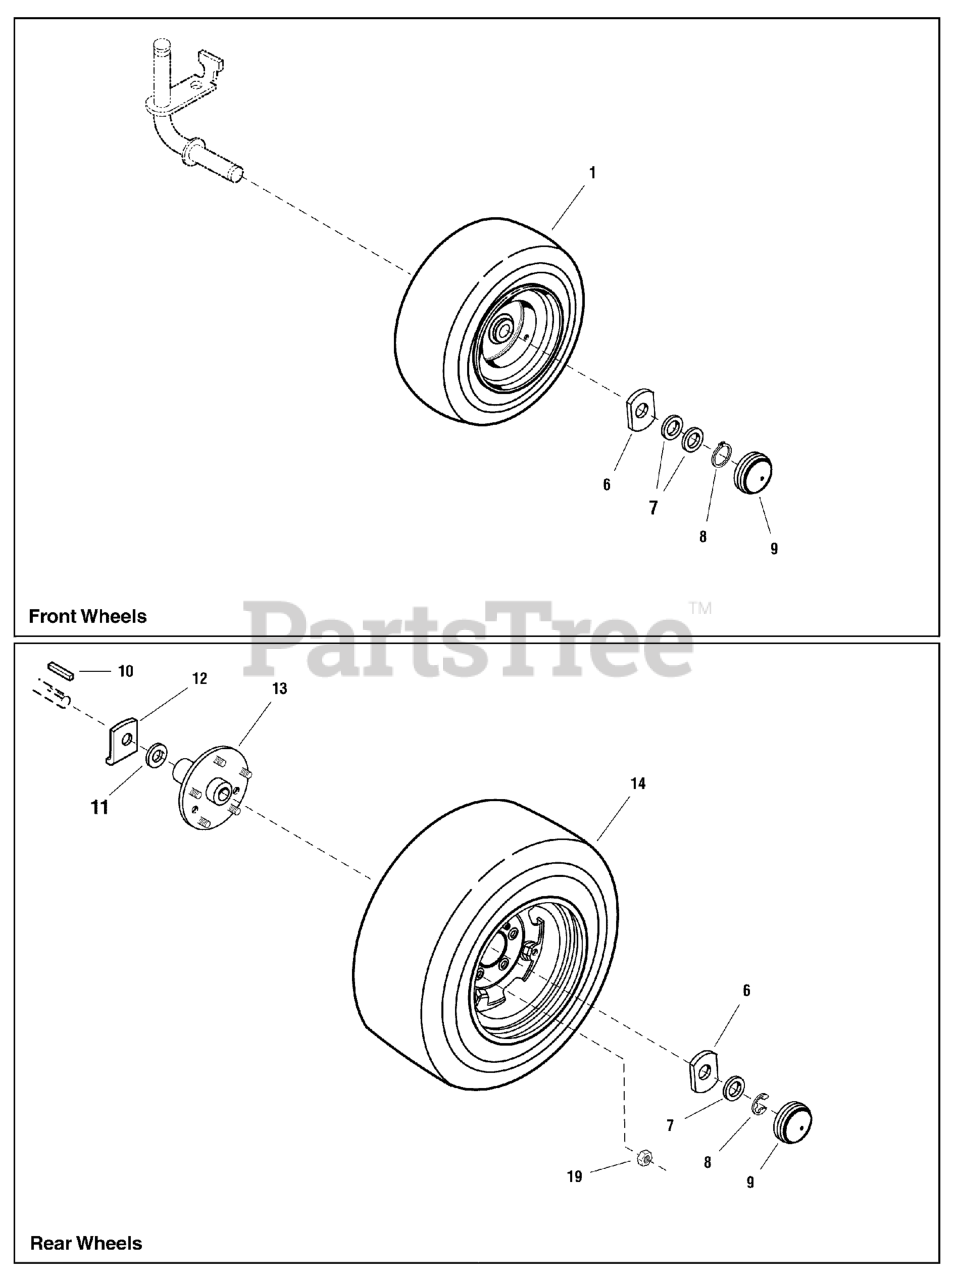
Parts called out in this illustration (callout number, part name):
1	WHEEL & TIRE ASSEMBLY, Front
6	WASHER, Special, 1 x 2-1/2
7	WASHER
8	RING, Retainer
9	CAP, Hub Grey, 2-23/64
10	KEY, HI PRO, 1/4 x 2
12	WASHER, Axle Seal
13	PLATE & HUB ASSEMBLY, Rear Wheel w/Studs
14	WHEEL & TIRE ASSEMBLY, Rear 24 x 12 x 12
19	NUT, Hex 7/16-20, For Wheel Bolt
